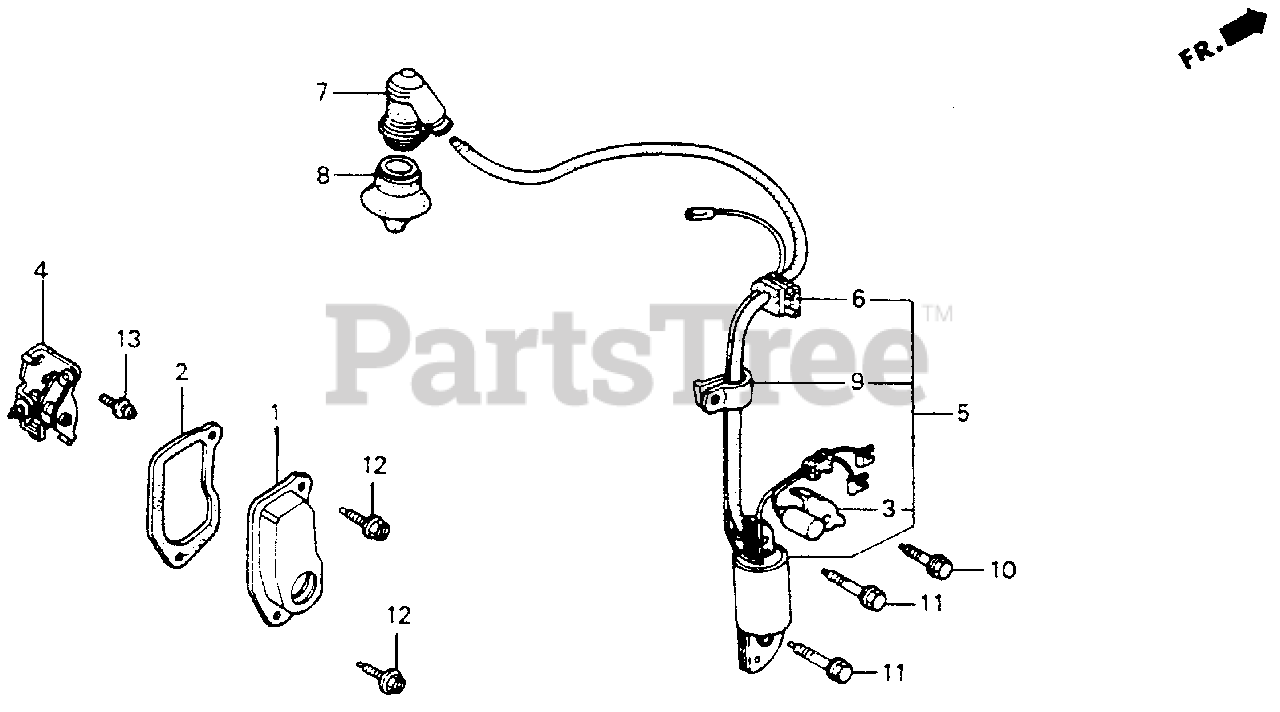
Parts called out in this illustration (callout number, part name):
1	COVER, BREATHER
2	GASKET, COVER
4	POINTS ASSY.
5	COIL ASSY., IGNITION (NOT AVAILABLE)
6	GROMMET, WIRE
7	CAP ASSY., NOISE SUPPRESSOR
8	SEAL, IGNITION
9	CLAMP, IGNITION WIRE
10	BOLT, FLANGE (6X12) (CT200)
11	BOLT, FLANGE (6X32)
12	BOLT, FLANGE (5X10)
13	SCREW-WASHER (5X12)
